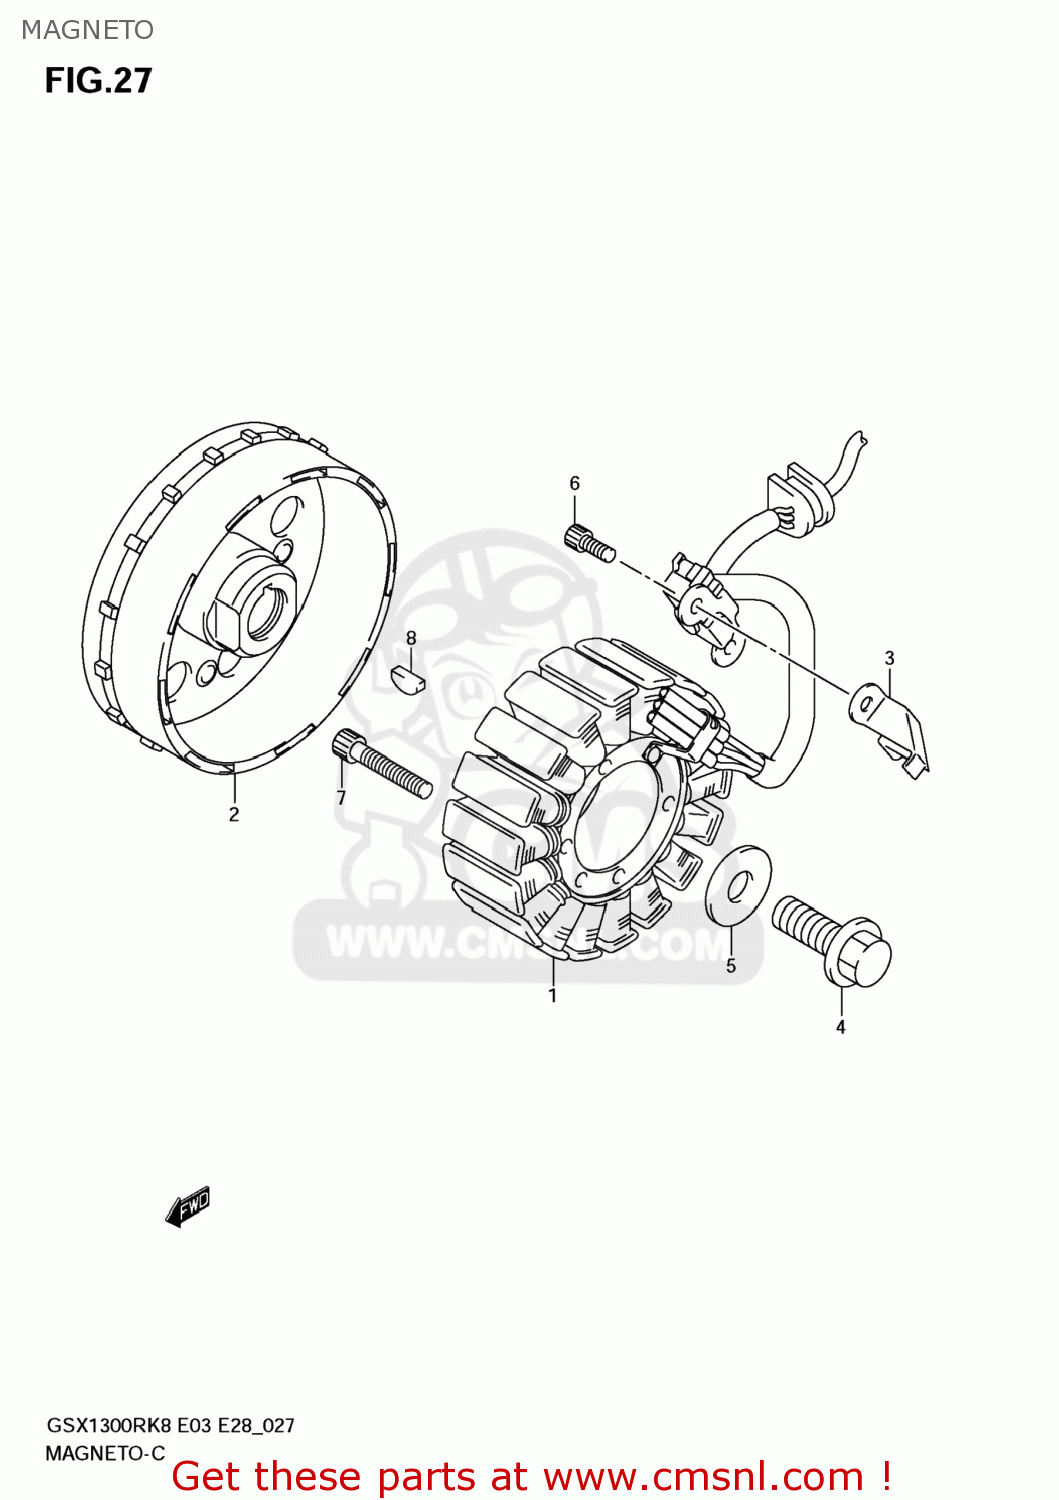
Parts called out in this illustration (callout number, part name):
1	STARTER ASSY
2	ROTOR ASSY
3	CLAMP,MAGNETO LEAD
4	BOLT(12X30)
5	WASHER(12X30X3)
6	BOLT
7	BOLT
8	KEY
